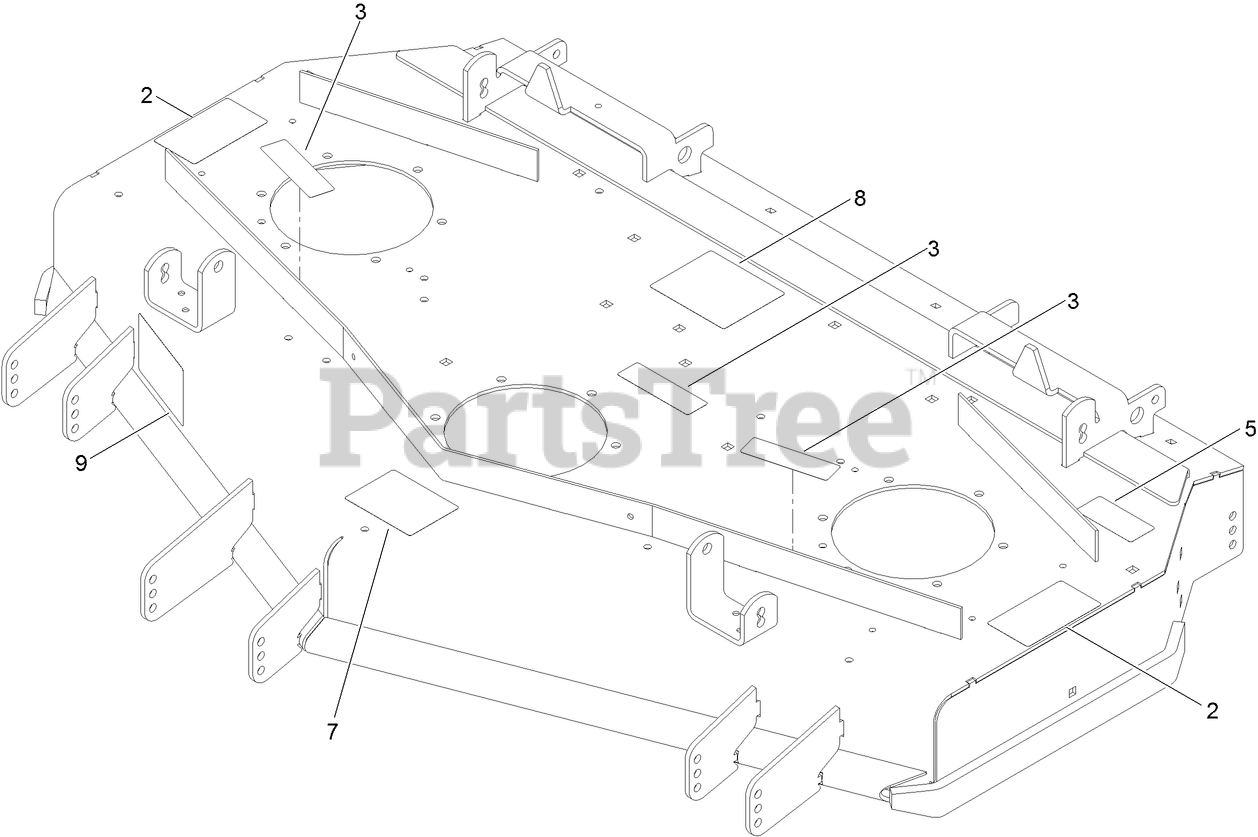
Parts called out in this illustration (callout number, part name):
2	DECAL-DANGER
3	DECAL-COVER, MISSING
5	DECAL-BOLT TORQUE
7	DECAL-SCALP, ANTI
8	DECAL-ROUTING, BELT
